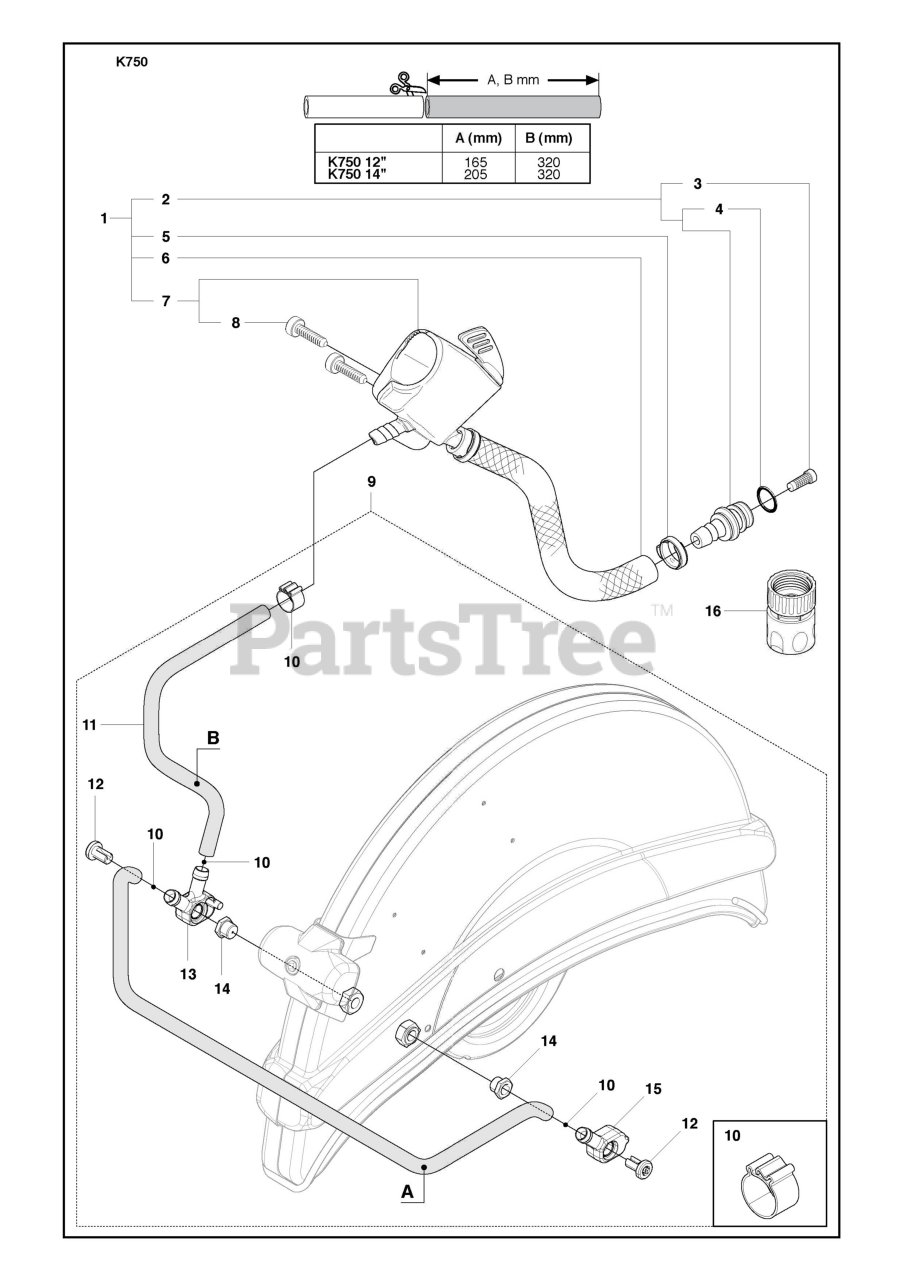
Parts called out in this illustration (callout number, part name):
1	Hose Kit
2	Nipple
3	Filter
4	O-Ring
5	Hose Clamp
6	Hose
7	Valve Assy
9	Hose Kit
10	Hose Clamp
11	Hose
16	Coupler
